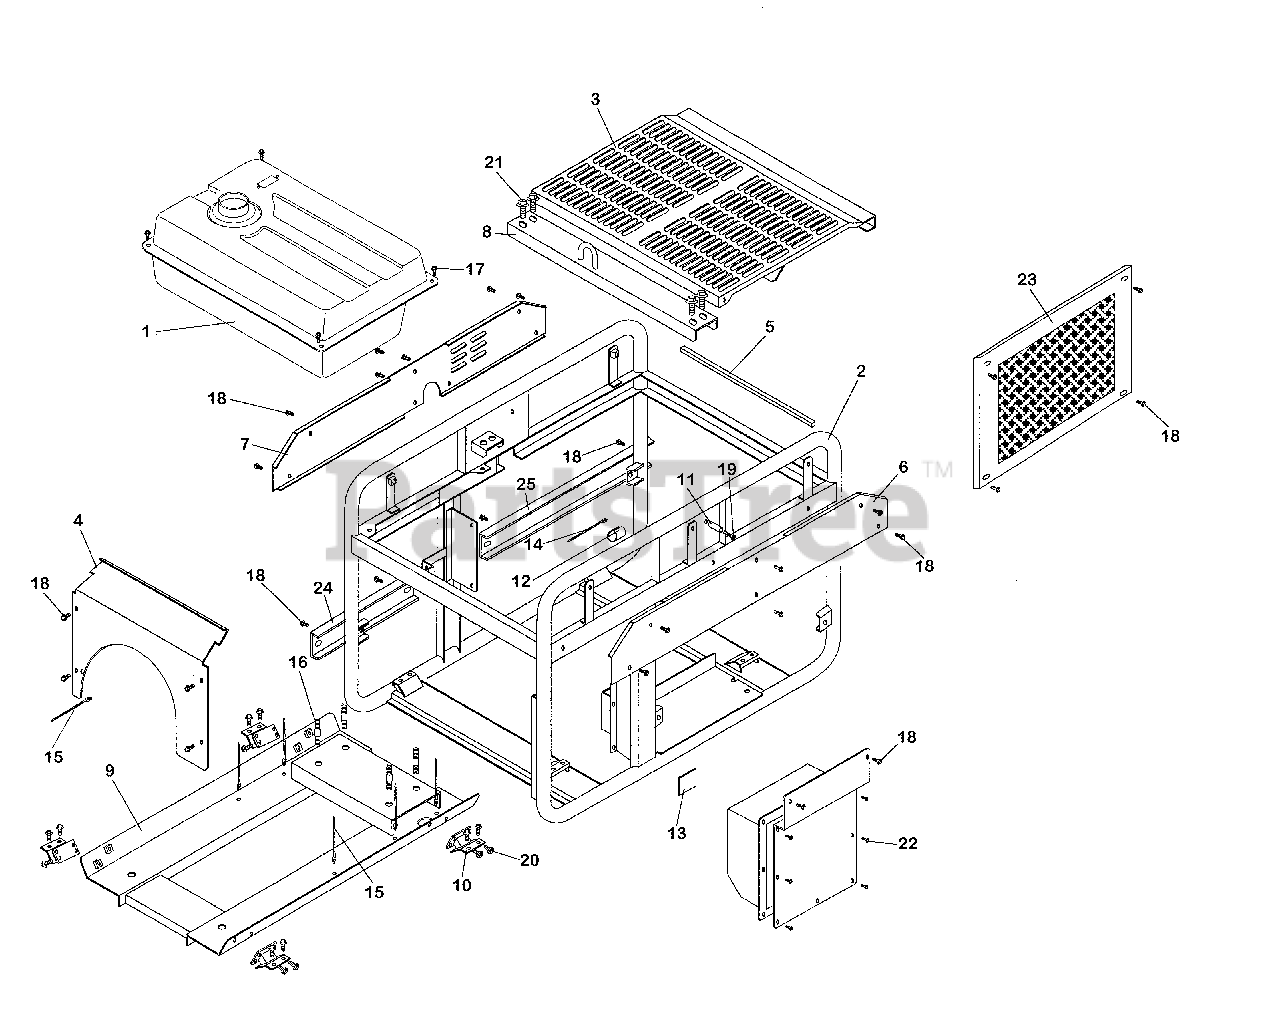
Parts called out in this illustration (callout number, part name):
1	TANK COMP,F*R280*
2	FRAME (WITHOUT MOUNTING TABS)
2	FRAME (WITH MOUNTING TABS FOR SIDE COVER & 2 PROTECTOR SUPPORTS)
3	COVER (UPPER)
4	PLATE, T.G.
5	SEAL, COVER (UPPER)
6	PLATE, L. UP
7	PLATE, R. SIDE
8	BEAM, HANGER
10	RUBBER, GENERATOR (LOWER)
14	TIE, CABLE
15	TIE, CABLE
16	BOLT, STUD (10X45)
17	BOLT-WASHER (5X14)
18	BOLT, FLANGE (6X12) Use up to Engine SN 1543277.
19	BOLT, FLANGE (6X25)
20	BOLT, FLANGE (8X16) Use from Engine SN 1000016.
21	BOLT, FLANGE (12X25)
22	BOLT, FLANGE (6X12) Use from Frame SN 1001725.
23	COVER, SIDE
24	SUPPORT A, PROTECTOR
25	SUPPORT B, PROTECTOR
NI	WHEEL KIT
